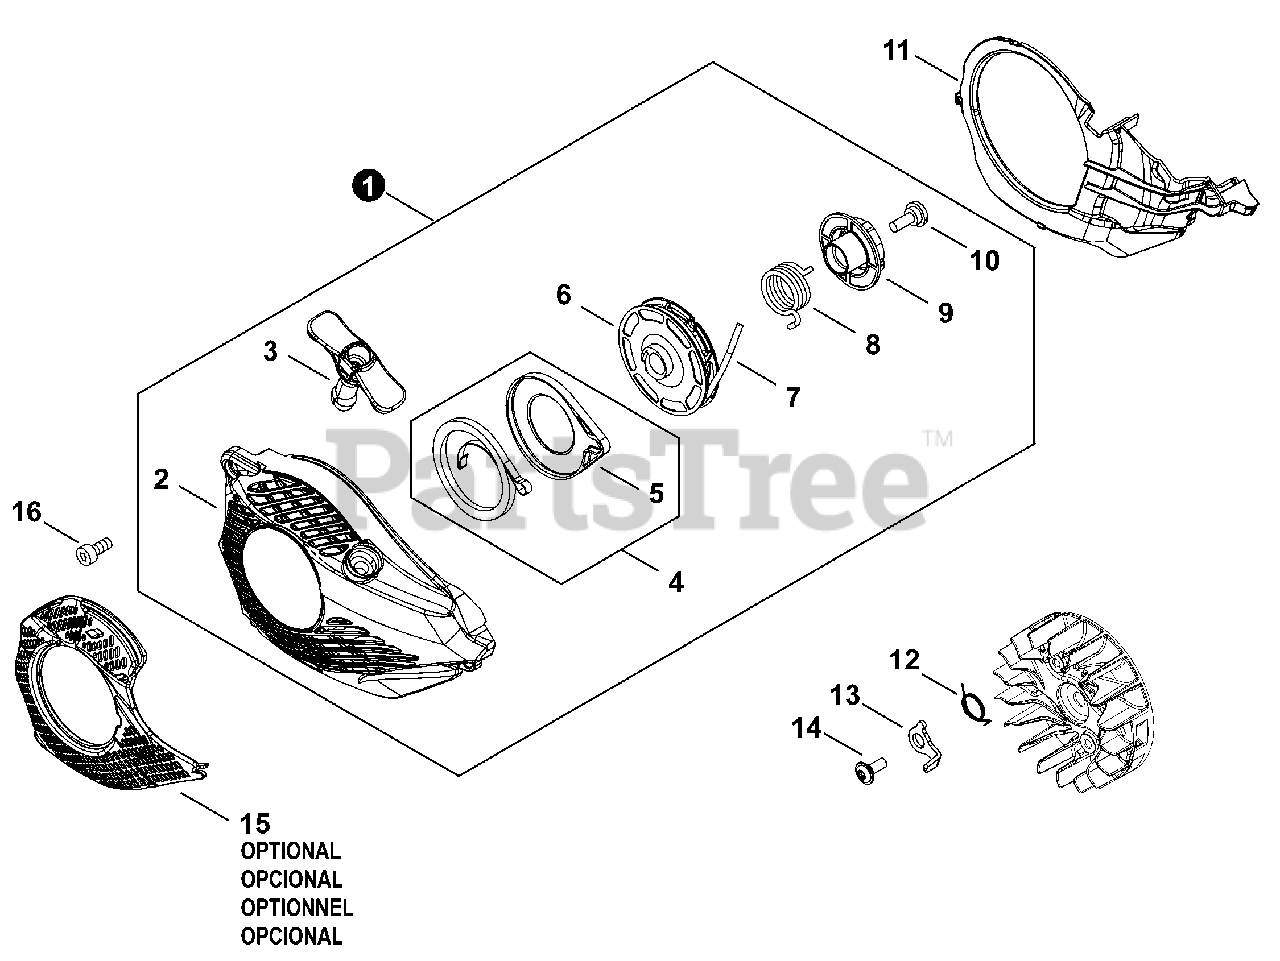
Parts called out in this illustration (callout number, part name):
1	STARTER ASSY
2	CASE ASSY, STARTER
3	GRIP, STARTER
4	SPRING KIT, REWIND
5	SPRING CASE
7	ROPE, STARTER 3×700
8	SPRING, RETURN
9	PLATE, CAM
10	SCREW
11	COVER, FAN
12	SPRING, TORSION
15	SHIELD, DEBRIS
16	BOLT, TORX 4×16
